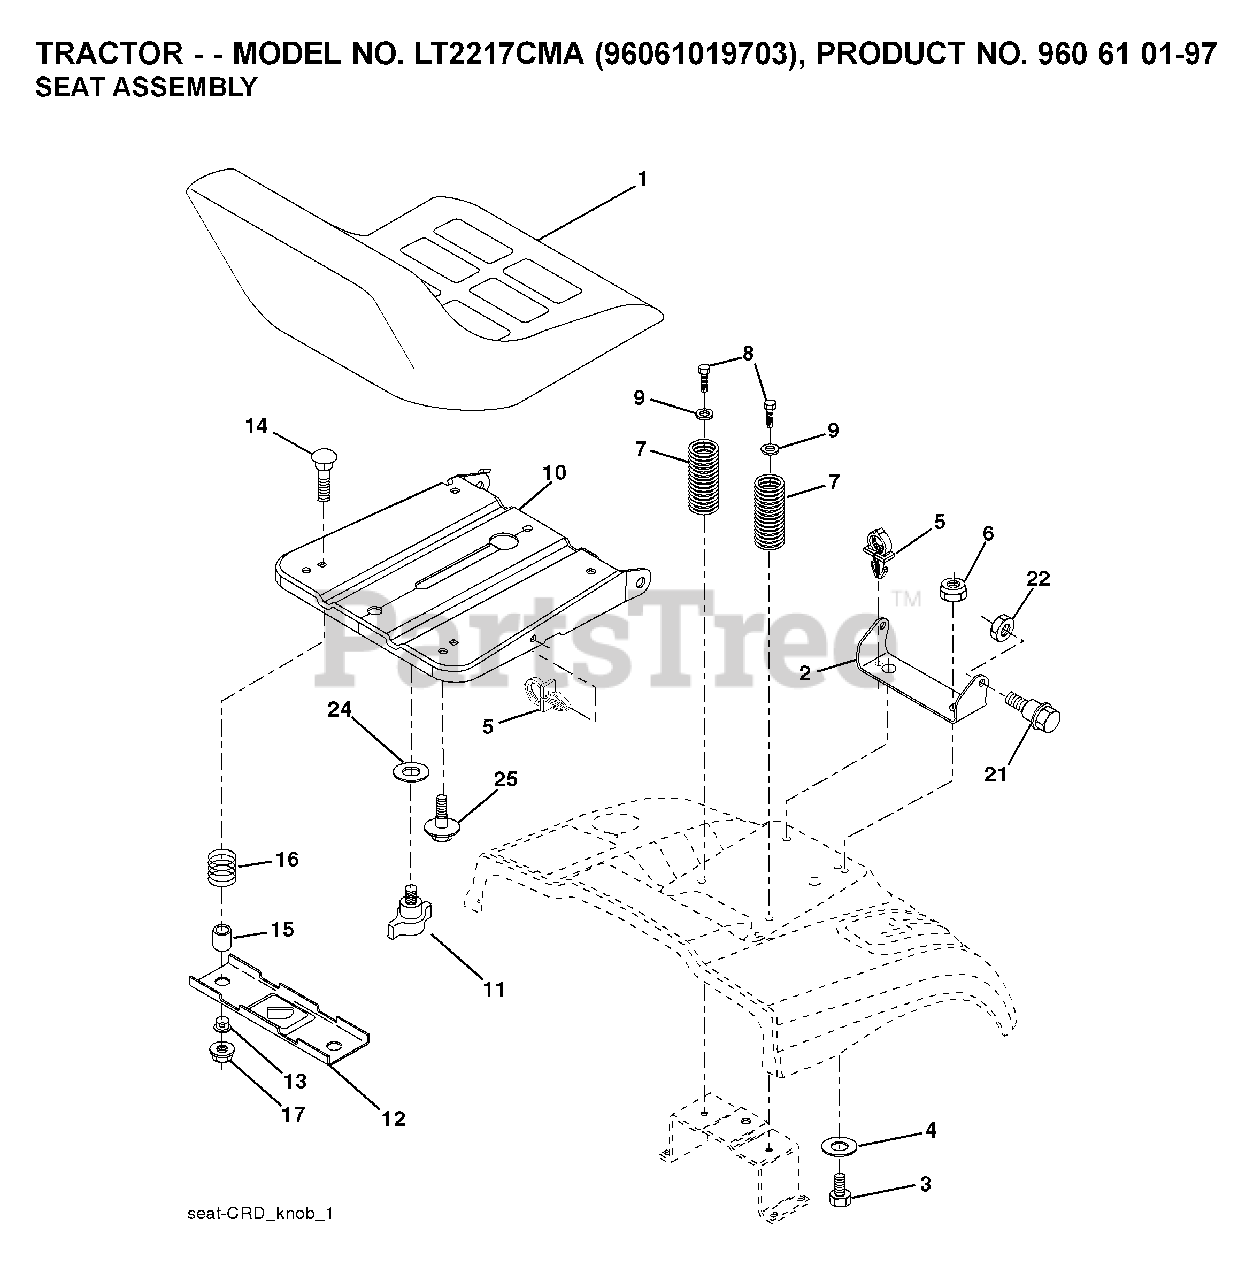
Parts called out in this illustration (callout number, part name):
2	SEAT PIVOT BRKT
4	WASHER PM
5	PUSH CLIP
6	NUT
7	SPRING COMPRESSION
8	SCREW 3/8-16X1
9	WASHER
10	PAN.ASM.SEAT.1SLOT
11	KNOB.SEAT.ADJ.WINGNUT
12	BRKT.MNTNG.SWITCH.SEAT
14	BOLT.ROUND.HEAD.SQUARE.NECK
15	SPACER SPLIT 28X.96
17	NUT T
21	BOLT.SHOULDER.5/16-18
22	NUT.71038.31-18.HEX.NYLOCK
25	BOLT,SHOULD
